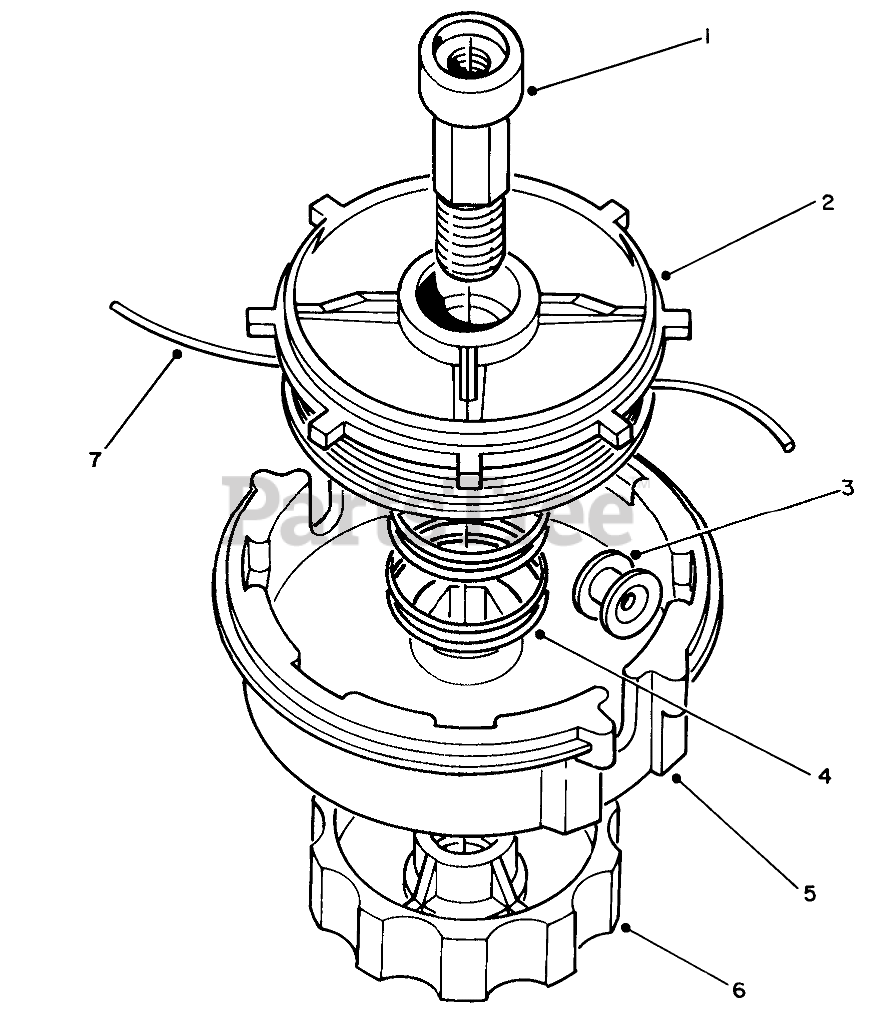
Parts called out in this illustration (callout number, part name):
1	SHAFT (SERVICE ONLY)
2	INNER SPOOL(SERV ONLY)
3	EYELET(SERVICE)
4	SPRING (SERVICE)
5	SPOOL HSG (SERVICE ONLY
6	LH KNOB(SERVICE ONLY)
7	.105 Line
